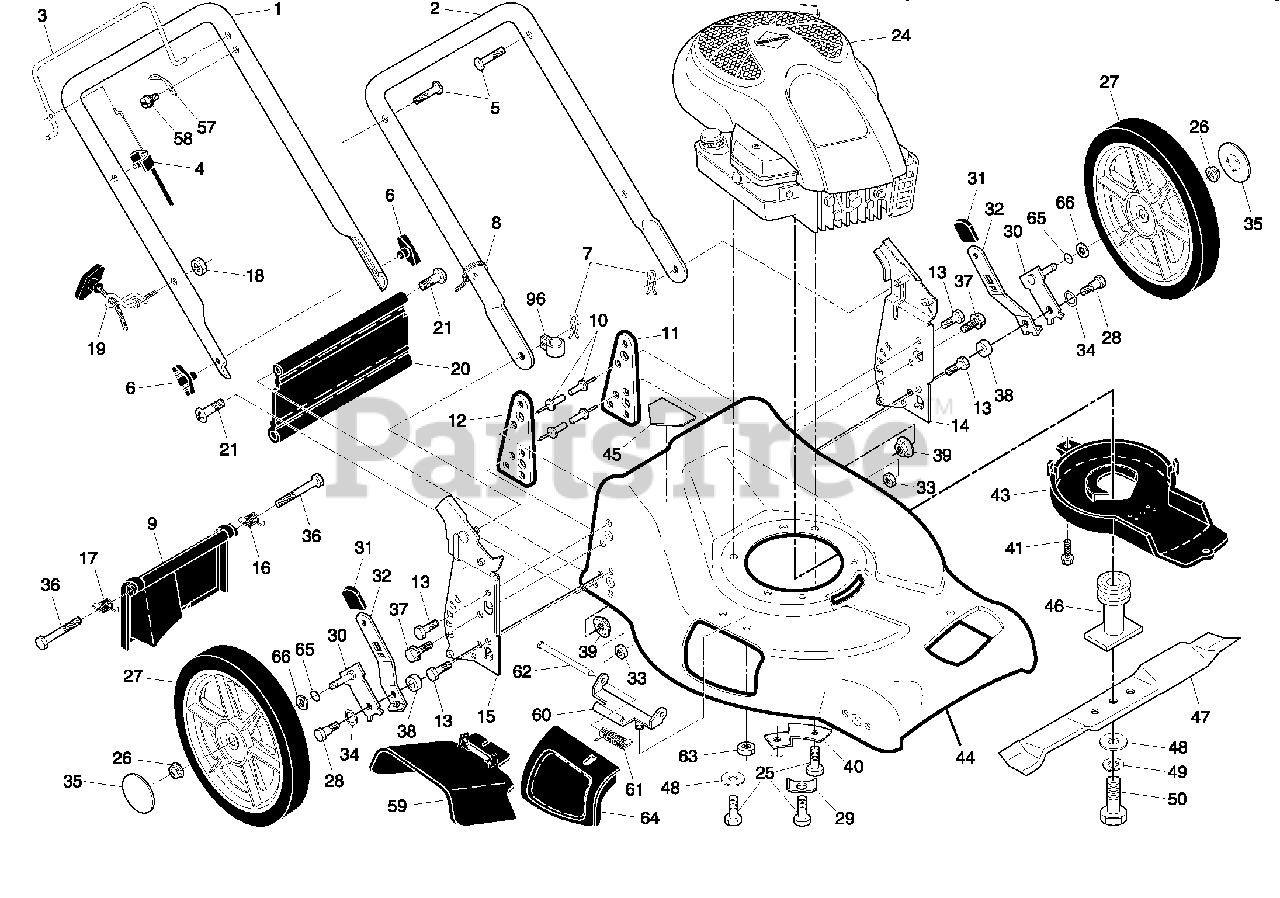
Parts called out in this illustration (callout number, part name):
1	Upper Handle
2	Lower Handle
3	Control Bar
4	Engine Zone Control Cable
5	Handle Bolt
6	Handle Knob
7	Hairpin Cotter
8	Wire Tie
9	Rear Door Assembly
10	Pop Rivet
11	Support Bracket, LH
12	Support Bracket, RH
13	Screw 1/4-20 x 5/8
14	Handle Bracket, LH
15	Handle Bracket, RH
16	Spring, Rear Door, LH
17	Spring, Rear Door, RH
18	Keps Locknut 1/4-20
19	Rope Guide
20	Rear Skirt
21	Hinge Screw 1/4-20 x 1-1/4
25	Screw, Hex Head, Threaded, Rolled 3/8-16 x 2
26	Nut, Hex, Flangelock 3/8-16
27	Wheel & Tire Assembly, Rear, 12"
28	Bolt, Shoulder 5/16-18
30	Axle Arm Assembly, Rear
31	Selector Knob
32	Selector Spring
33	Nut, Hex, Nylock 5/16-18
34	Washer, Curved, Cylindrical
35	Hubcap
36	Bolt, Rear Door
37	Thread Cutting Screw w/Sems 5/16-18 x 3/4
38	Spacer
39	Nut, Hex
40	Mounting Bracket, Debris Shield
41	Screw, Debris Shield
43	Debris Shield
44	Kit, Housing
45	Danger Decal
46	Blade Adapter / Pulley
47	Blade, 21"
48	Hardened Washer
49	Helical Washer 3/8
50	Blade Bolt, Hex Head, Grade 8
57	Bracket, Upstop
58	Screw
59	Discharge Defl ector
60	Hinge Bracket
61	Spring
62	Rod, Hinge
63	Nut, Hex
64	Mulcher Door
65	O-Ring
66	Washer, Flat 1/2
96	Clip, Cable
96	Operator's Manual, English
96	Operator's Manual, French
96	Repair Parts Manual
